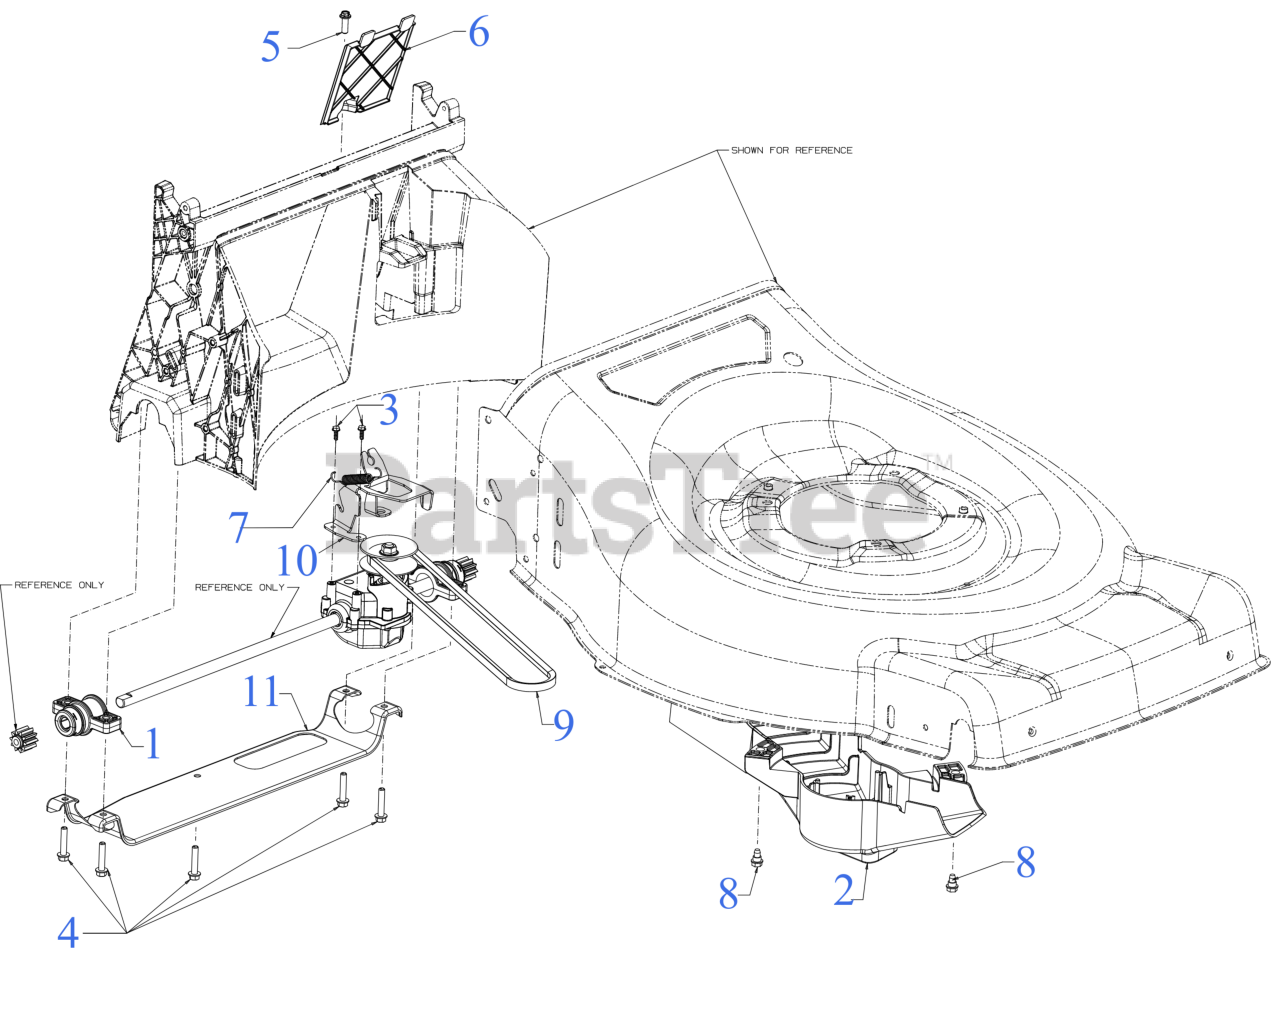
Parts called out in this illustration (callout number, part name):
1	BEARING ASSEMBLY
2	23" BAFFLE (CENTER)
3	SCREW .159 x .43
4	SCREW 1/4-15 x 1.250
5	SCREW 1/4 x .750
6	23" BAFFLE DOOR
7	EXTENSION SPRING 2.675"
8	SHOULDER SCREW 1/4-20 x .50
9	V-BELT 3L x 33.25"
10	TRANSMISSION BRACKET
11	23" SUPPORT BRACKET
